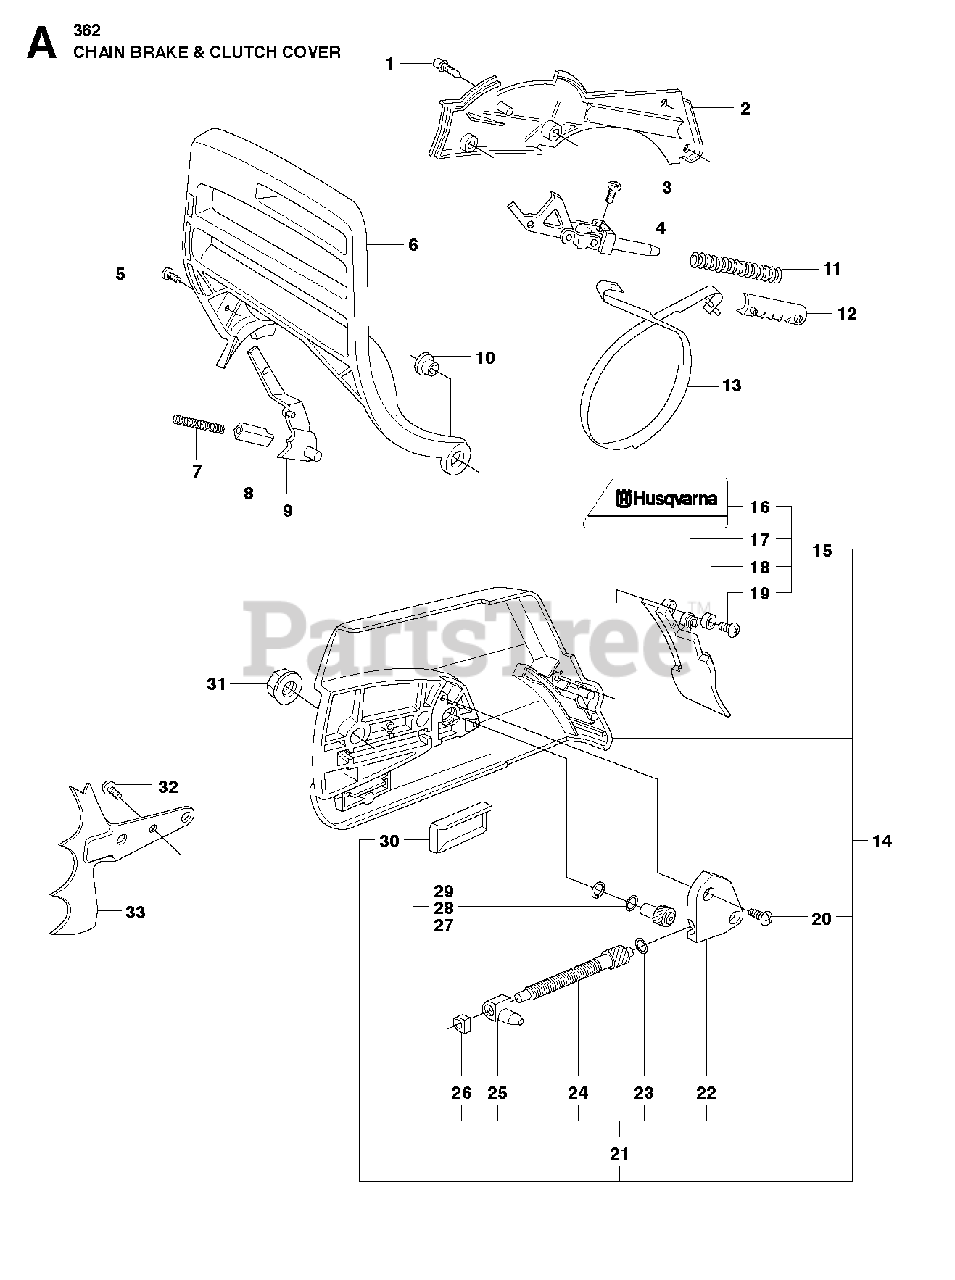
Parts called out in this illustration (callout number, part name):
1	SCREW
7	LOCK SPRING
9	BRAKE LEVER
11	BRAKE SPRING
13	BRAKE BAND
14	CHAIN BRAKE COVER
15	CHAIN BRAKE COVER
16	DECAL
17	PROTECTOR
18	WASHER
19	SCREW
20	SCREW
21	KIT-CHAIN TENSIONER
22	COVER
23	WASHER
24	WORM SCREW / ADJUSTER
25	PAWL
26	SLEEVE
27	WORM WHEEL
28	WASHER
29	O-RING
30	CHAIN GUIDE
31	NUT M8 FLANGE
33	SPIKE OUTER
